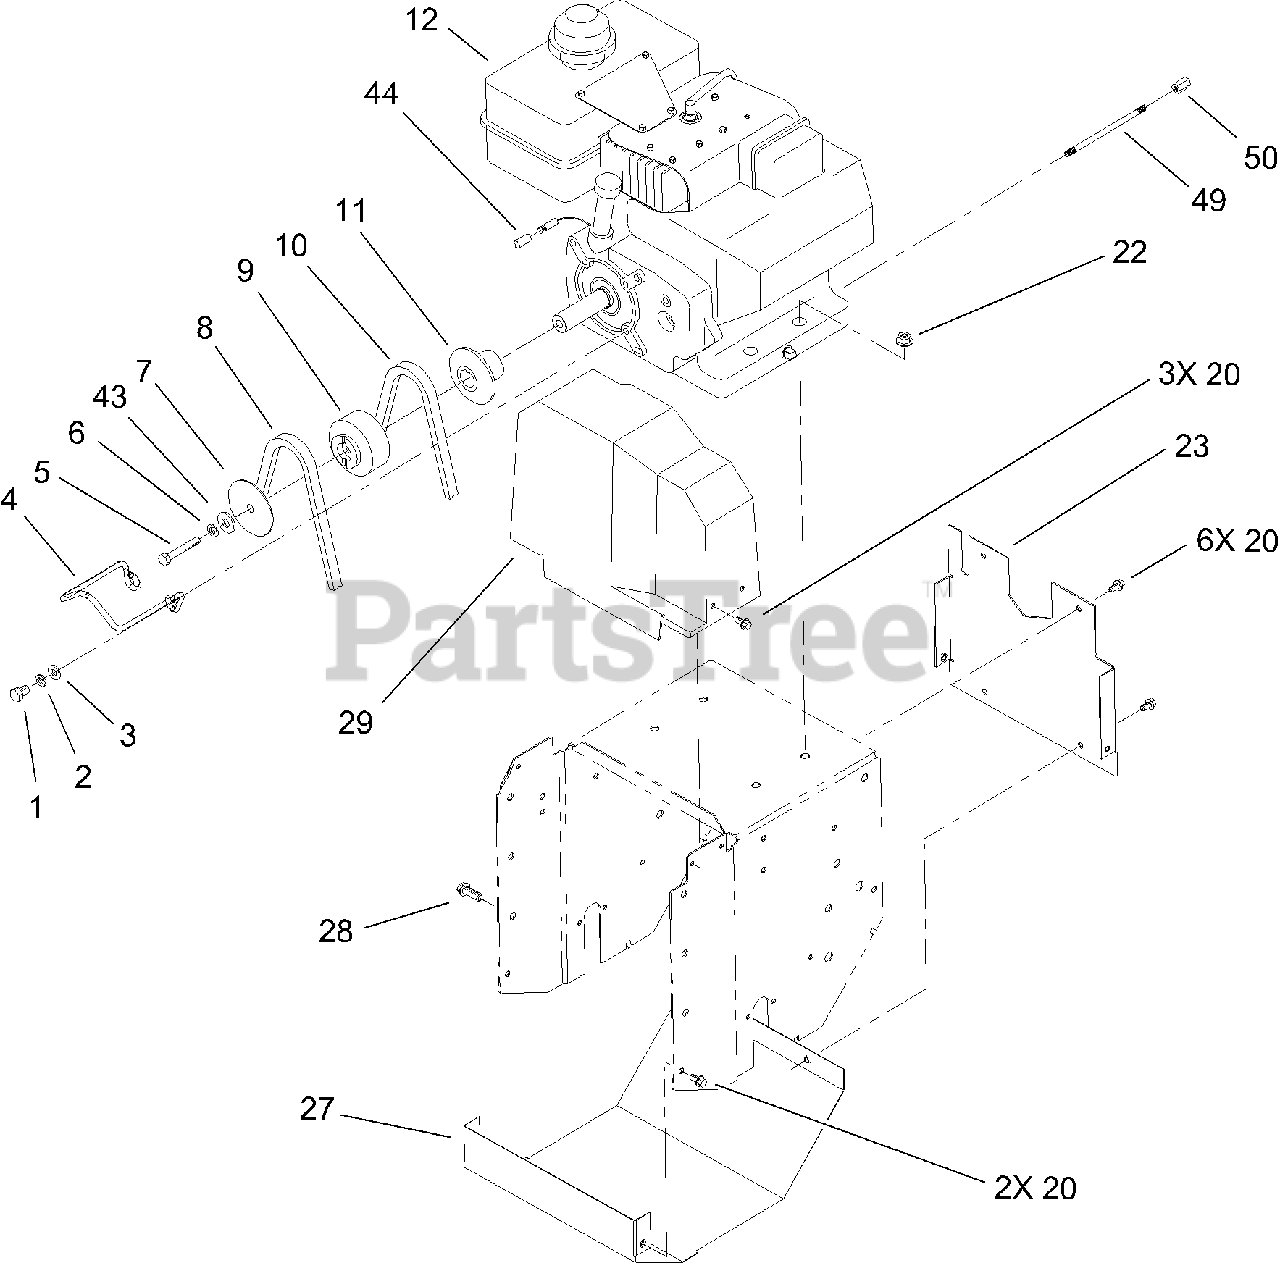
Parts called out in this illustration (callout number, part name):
1	SCREW-HH
2	WASHER-LOCK
3	WASHER-FLAT
4	GUIDE-BELT
5	SCREW-HH
6	WASHER-LOCK
7	SHEAVE-HALF, IMPELLER
9	PULLEY-ENGINE CENTER
10	V BELT-TRACTION
11	SHEAVE-HALF, TRACTION
20	SCREW-HWH
23	PLATE-BACK
27	COVER-TRACTION, LOWER
28	SCREW-HWH
29	COVER-UPPER BELT
44	CAP-WIRE, LITE
49	NIPPLE-PIPE
50	CAP-PIPE
